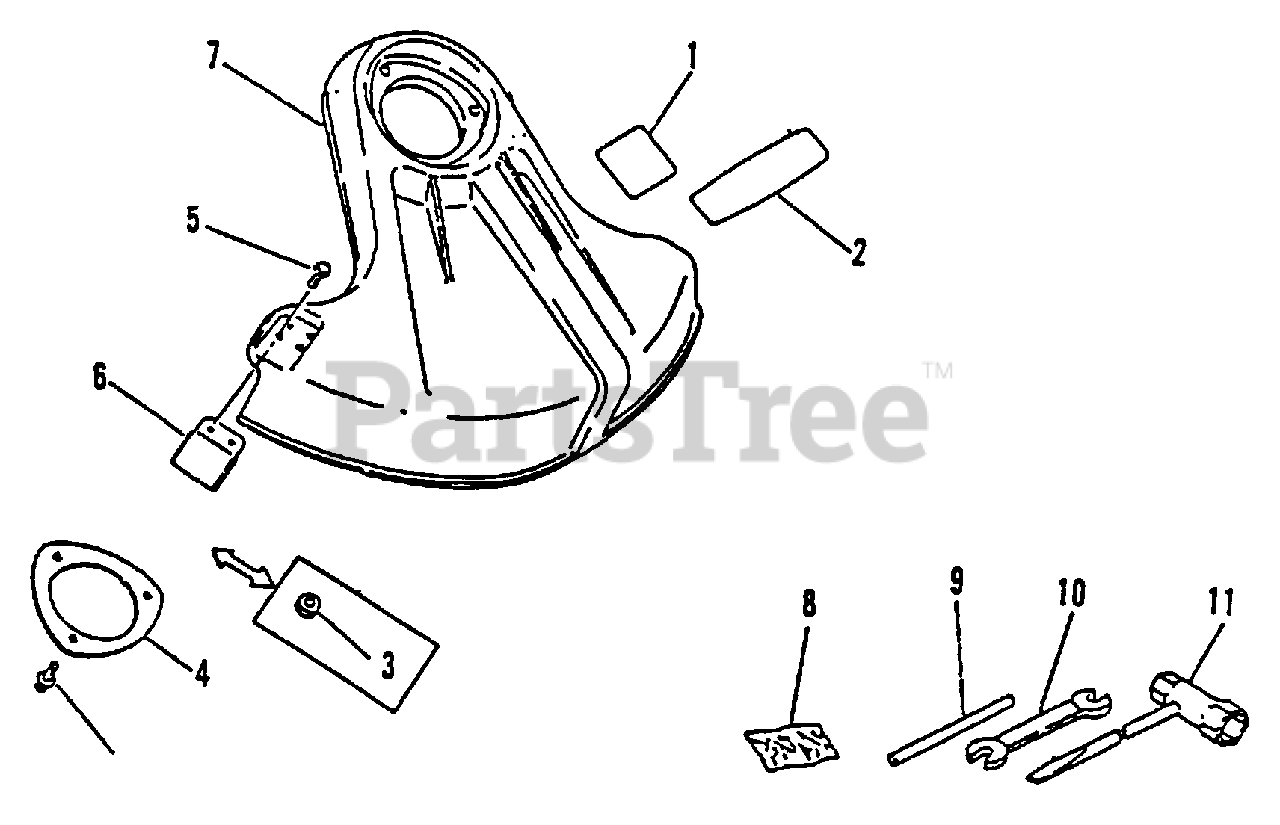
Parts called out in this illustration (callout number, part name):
1	LABEL - CAUTION
2	LABEL - ECHO
4	PLATE, SHIELD
5	SCREW - 5X16
6	KNIFE, TRIMMER LINE
7	DEBRIS SHIELD KIT
8	PIN, SPLIT - 2X22
9	LOCKING TOOL
10	SPANNER - 8X10mm
11	T-WRENCH - 17X19mm
